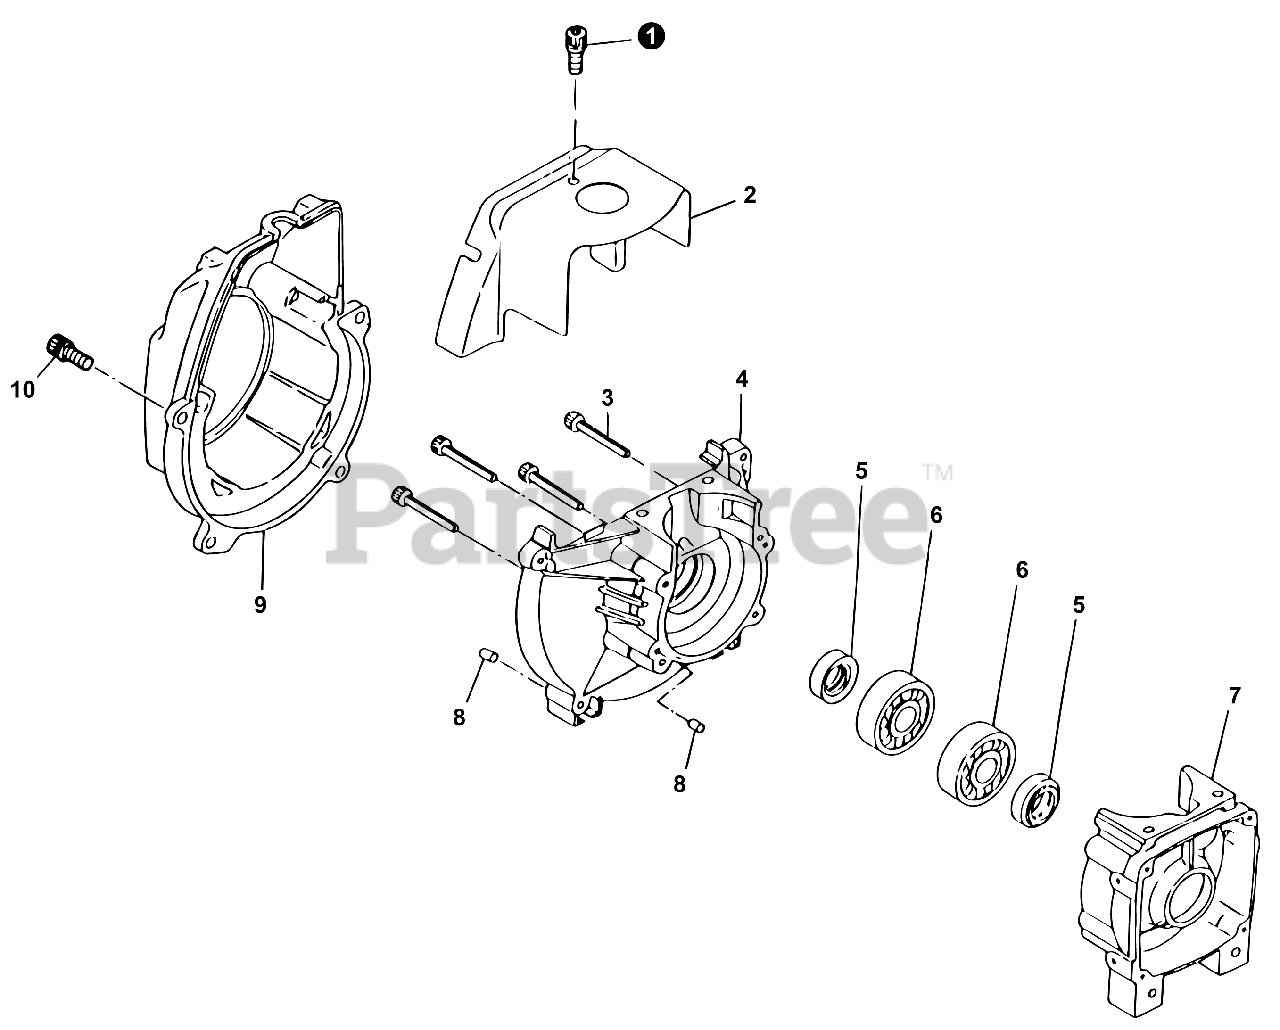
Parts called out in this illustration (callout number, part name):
1	BOLT 5×14
2	COVER, ENGINE
3	BOLT 5×30
4	CRANKCASE M
5	SEAL, OIL 16
6	BEARING, BALL 6202 C3
7	CRANKCASE S
8	PIN, LOCATING 5×10
9	COVER, FAN
10	BOLT M5×20
